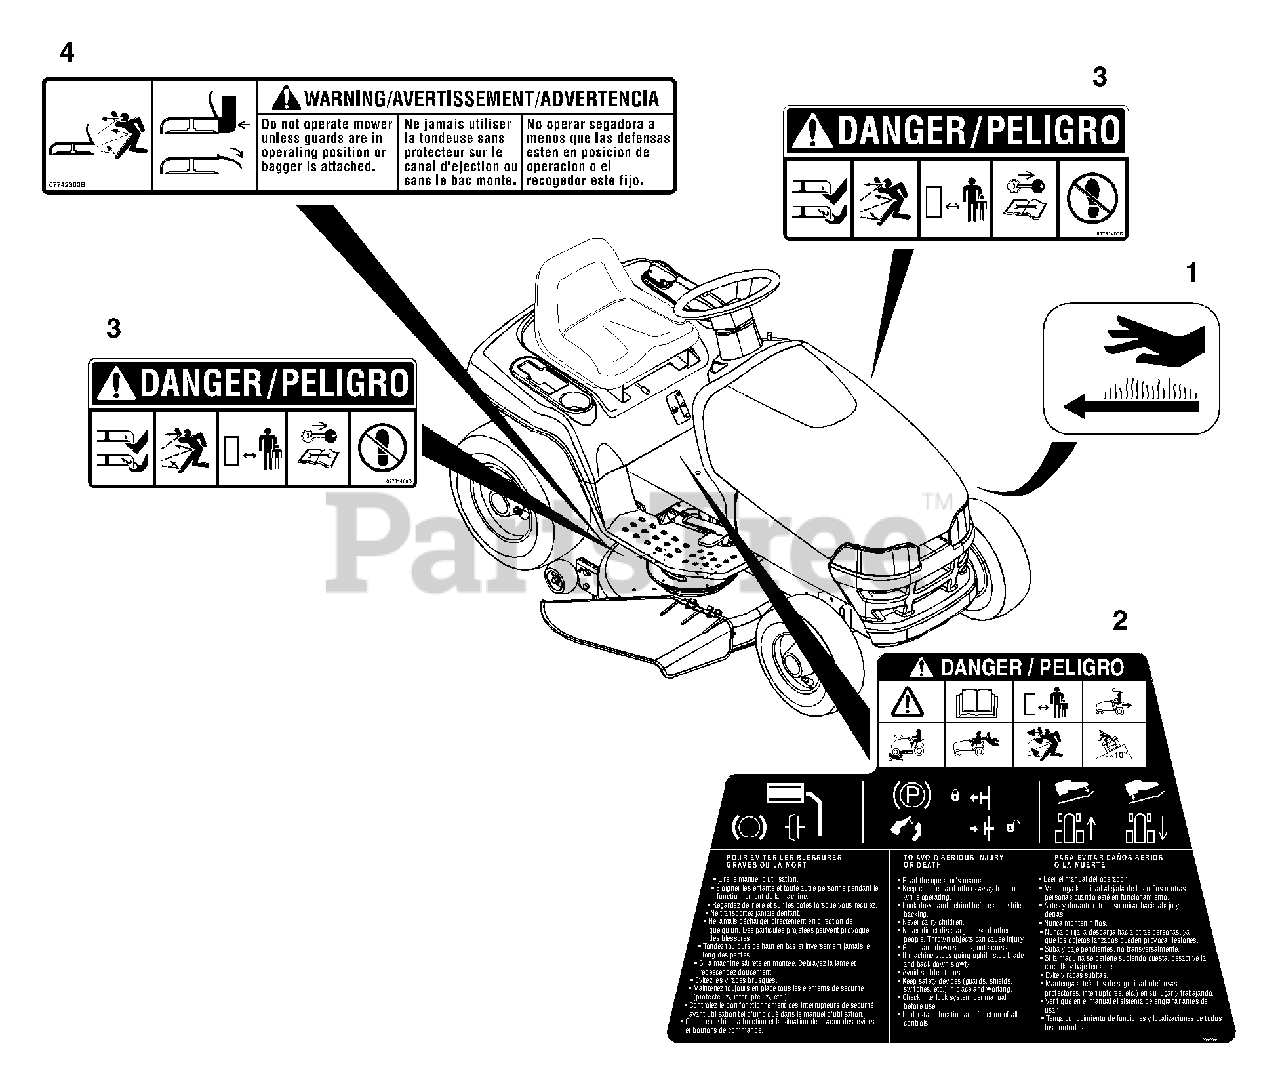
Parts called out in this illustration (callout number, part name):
1	DECAL, HOT SURFACE
2	DECAL-OPER INST YT
3	DECAL, MOWER PAN DANGER
4	DECAL, WARNING
